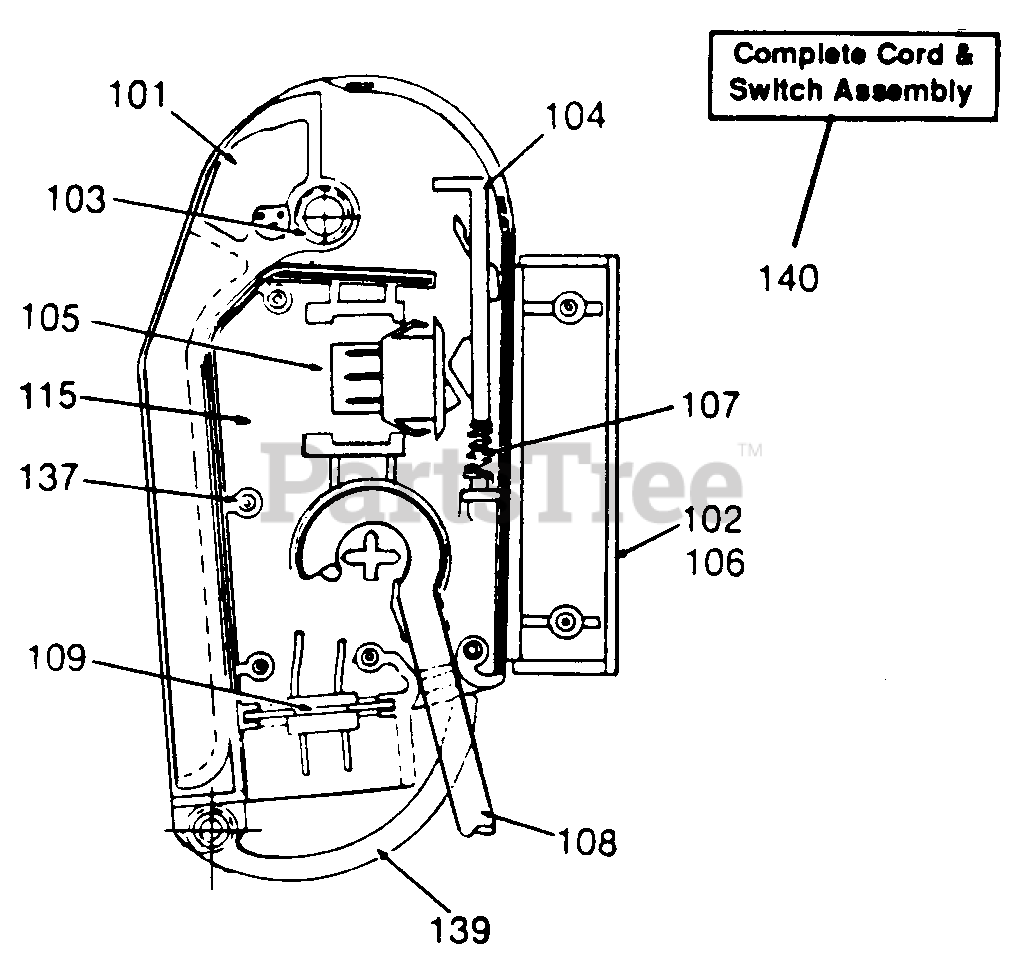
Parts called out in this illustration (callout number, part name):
101	Handle-Switch
102	Housing-Upper Half
103	Spring
104	Latch
105	Switch
106	Housing-Lower Half
107	Latch Spring
108	Cord Assembly
109	2-Prong Plug
115	Jumper Wire Ass'y.
139	Plug Retainer
140	Cord & Switch Box Ass'y. (Complete)
